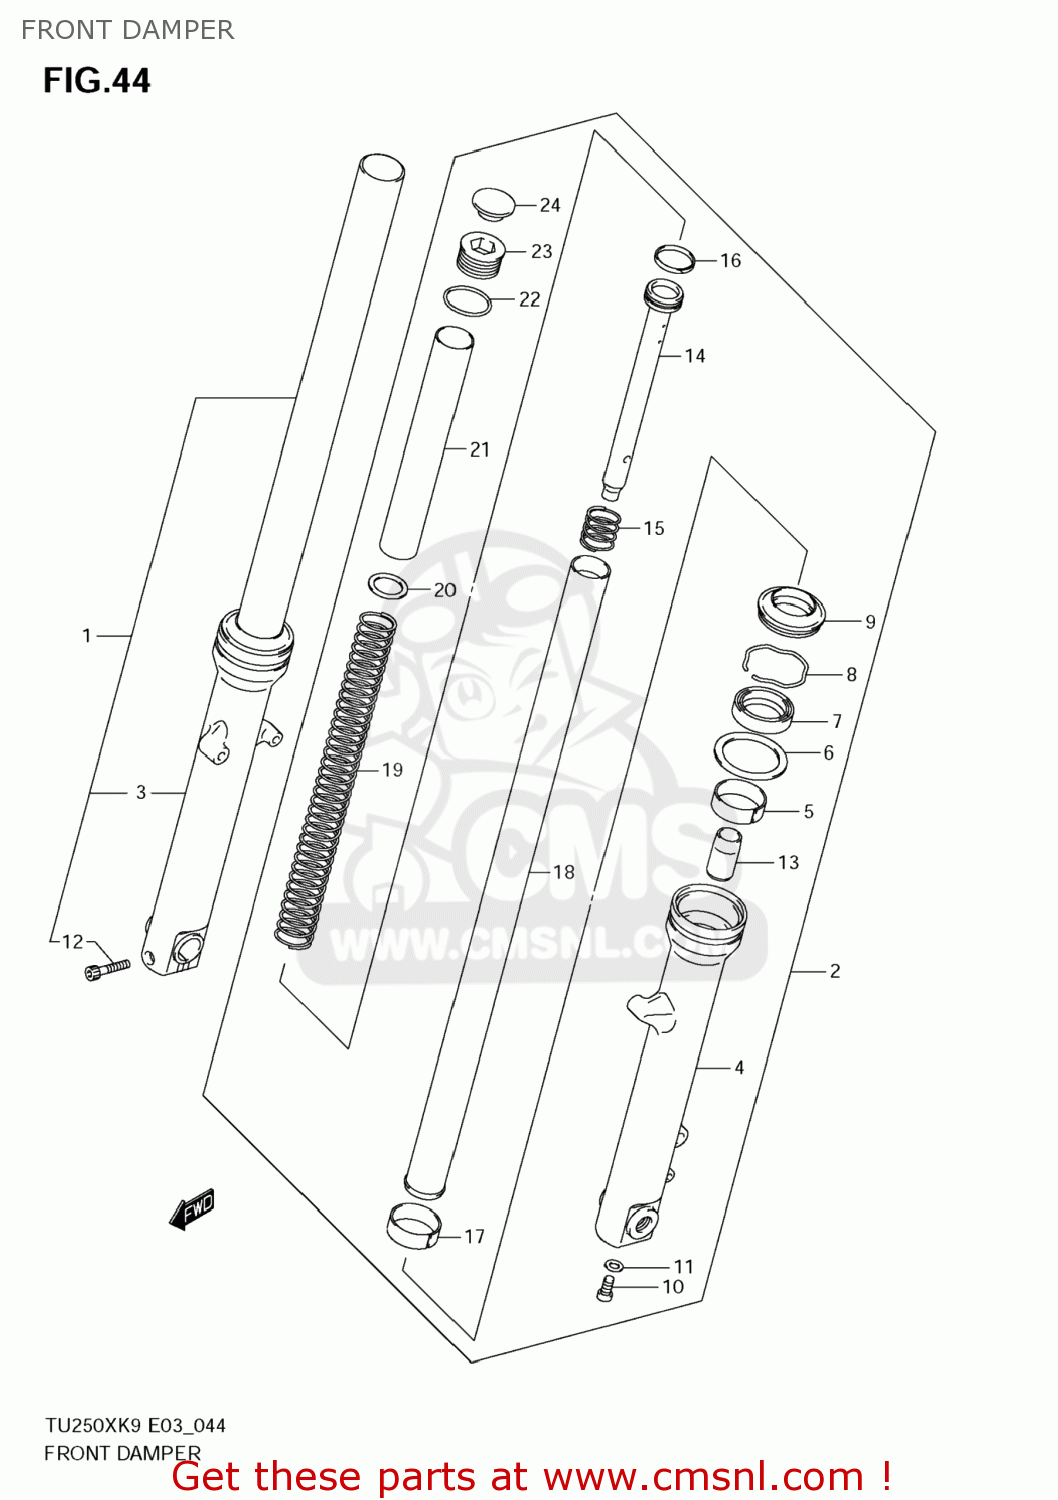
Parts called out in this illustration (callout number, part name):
1	DAMPER ASSY,FR FORK,R
2	DAMPER ASSY,FR FORK,L
3	TUBE,OUTER,R
4	TUBE,OUTER,L
5	BUSH,GUIDE
6	SPACER,SEAL
7	OIL SEAL,FRONT FORK
8	RING,STOPPER
9	SEAL,DUST
10	BOLT(8X27)
11	GASKET (NAS)
12	BOLT
13	PIECE,OIL LOCK
14	CYLINDER
15	SPRING,REBOUND
16	RING,PISTON
17	BUSH,SLIDE
18	TUBE,INNER
19	SPRING,MAIN
20	JOINT,SPRING
21	SPACER,SPRING
22	O RING
23	BOLT,FORK
24	CAP,FORK
